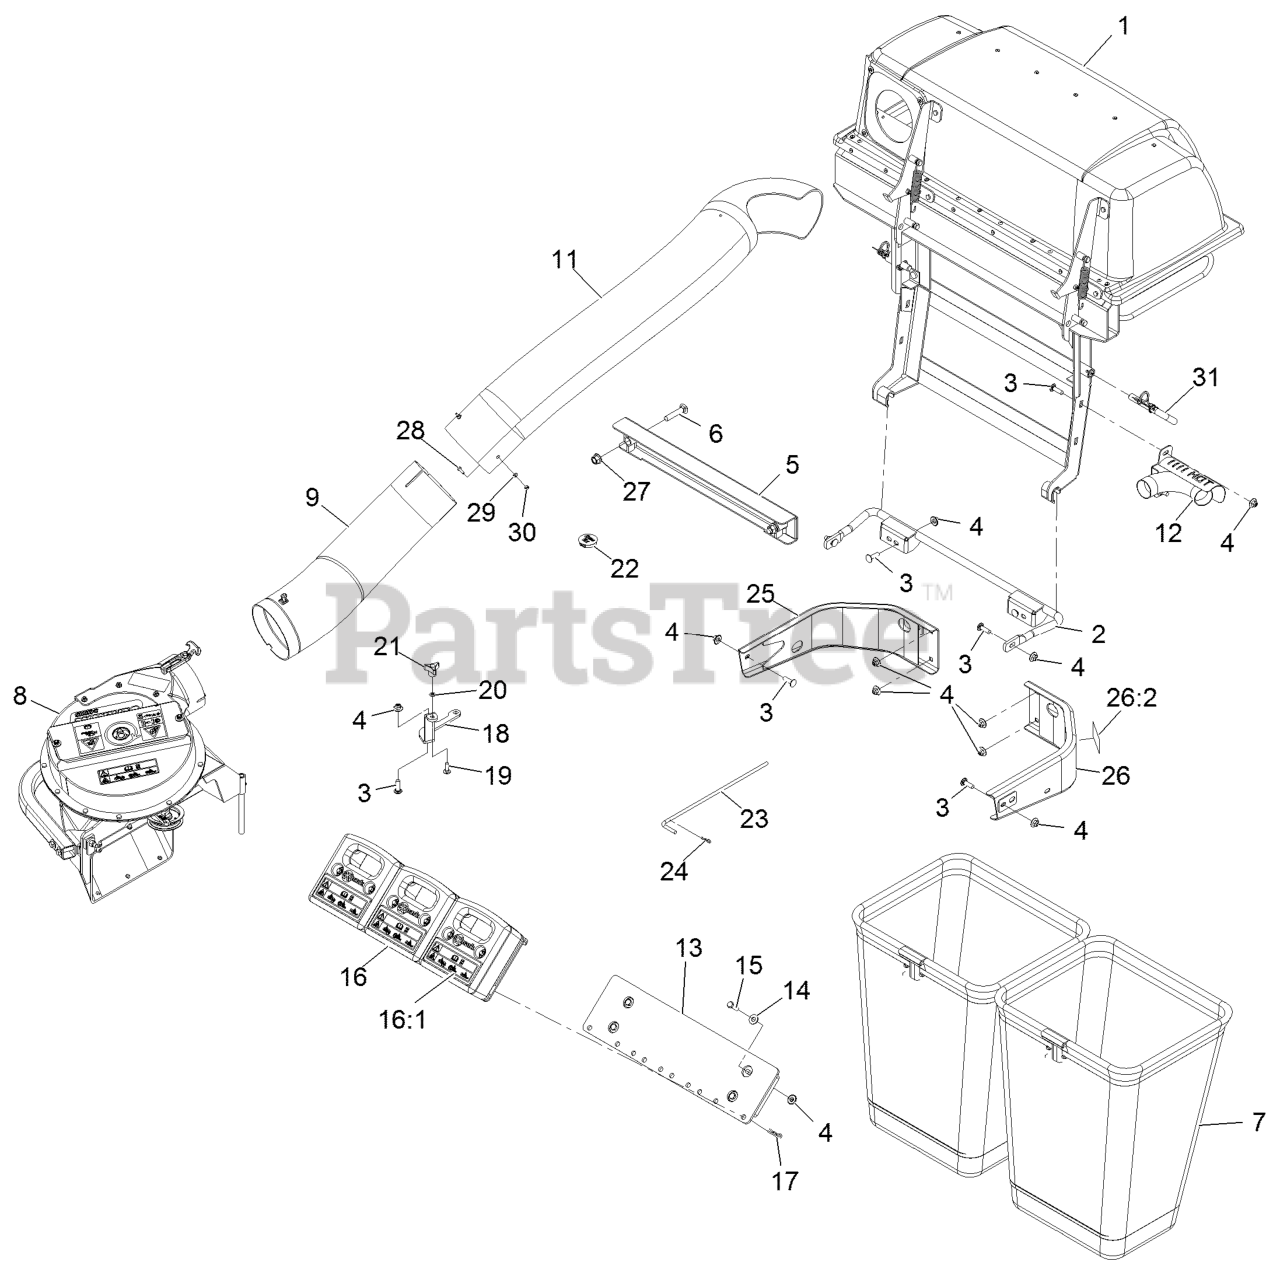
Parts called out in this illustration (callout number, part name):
2	MOUNT-BAGGER, LOWER
3	Bolt-Carriage 3/8-16 X 1 1/4
4	Nut-Nyloc 3/8-16 Flg
5	MOUNT-BAGGER, UPPER
6	SCREW-CARR
7	BAG AND FRAME ASM
8	ASM, BLOWER SMALL - SVC O
9	LOWER TUBE ASM
11	TUBE-UPPER
12	EXHAUST DIVERTER ASM
13	WLD, MOUNT TOEBOARD WEIGH
14	WASHER-FLAT
15	SCREW-HH
16	ASM,CAST WEIGHT
16:1	DECAL-WARNING WEIGHT
17	PIN-HAIR
18	BRACKET, SMALL UV BELT CO
19	BOLT-CARR
20	RING-RETAINING, BOLT
21	KNOB-3 PRONG
22	PLUG, BLACK NYLON 1.75
23	PIN,CHUTE PIVOT
24	PIN-COTTER
25	BUMPER-RH
26	LH BUMPER ASM
26:2	DECAL-WARNING
27	Nut-Lock 1/2-13
28	SCREW-HWH
29	WASHER-FLAT
30	NUT-LOCK, NI
31	PIN-MOUNT, BAGGER
